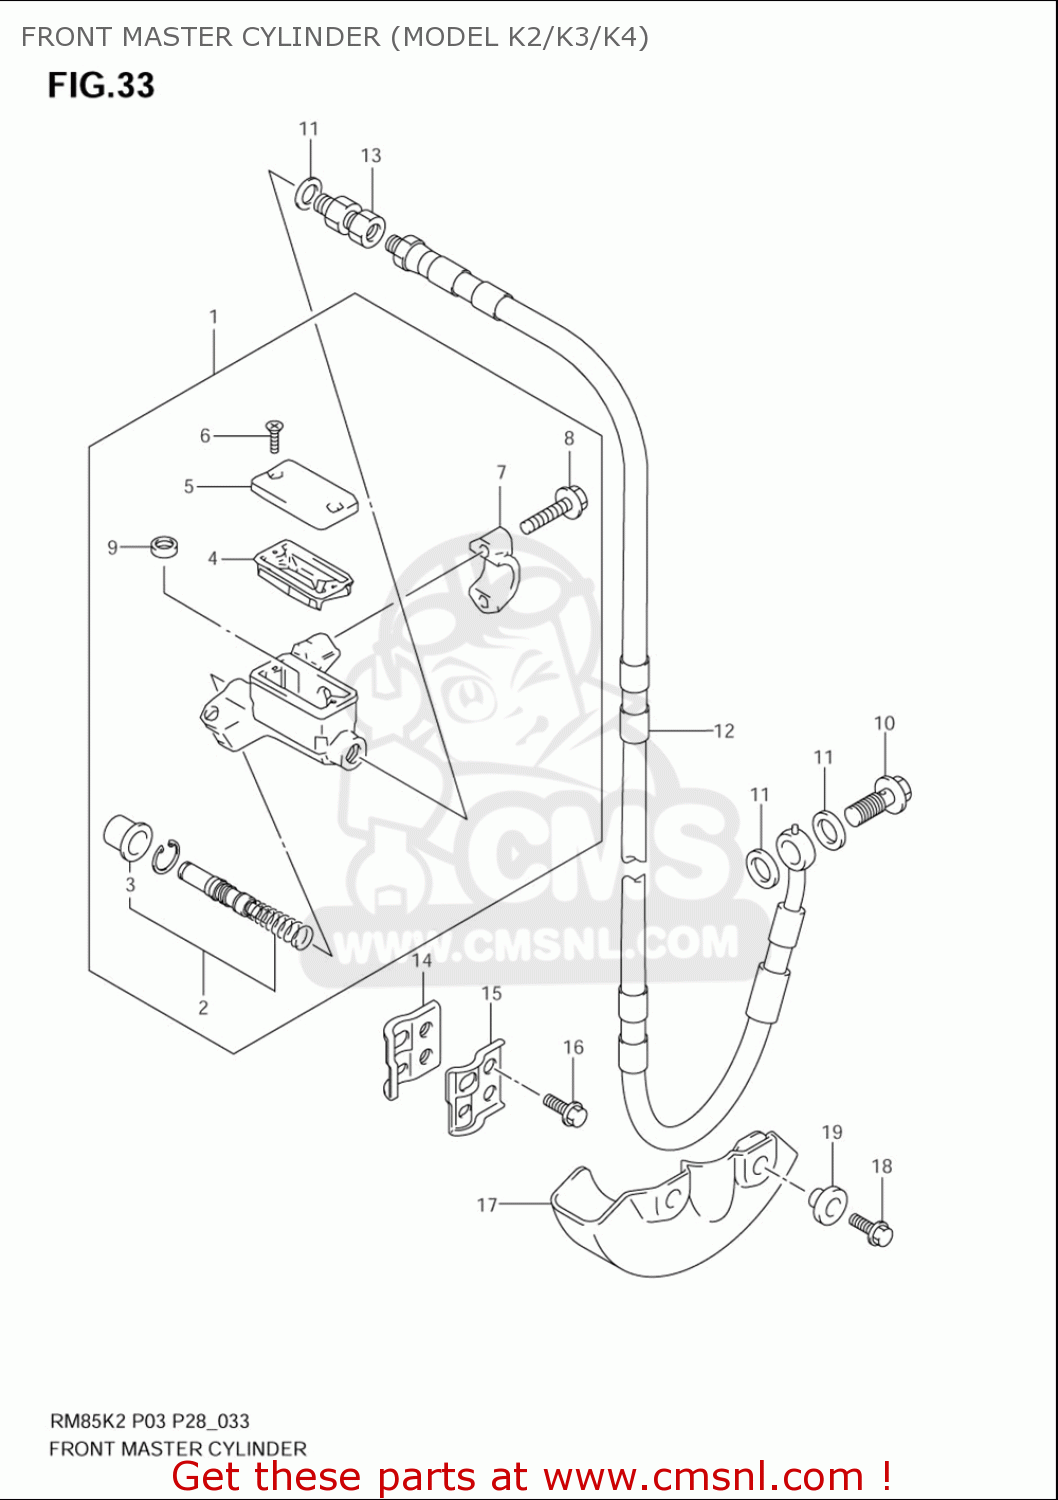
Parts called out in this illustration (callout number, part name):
1	CYLINDER ASSY,FR MASTER
2	PISTON & CUP SET
3	BOOT
4	DIAPHRAGM
5	CAP
6	SCREW
7	HOLDER
8	BOLT
9	SEPARATOR
10	BOLT UNION
11	WASHER(10X15X1.5)
12	HOSE,FR BRAKE
13	ADAPTOR,BRAKE HOSE
14	CLAMP,FR BRAKE HOSE INNER
15	CLAMP,FR BRAKE OUTER
16	BOLT(6X16)
17	COVER,FR BRAKE HOSE
18	BOLT(6X12)
19	WASHER
